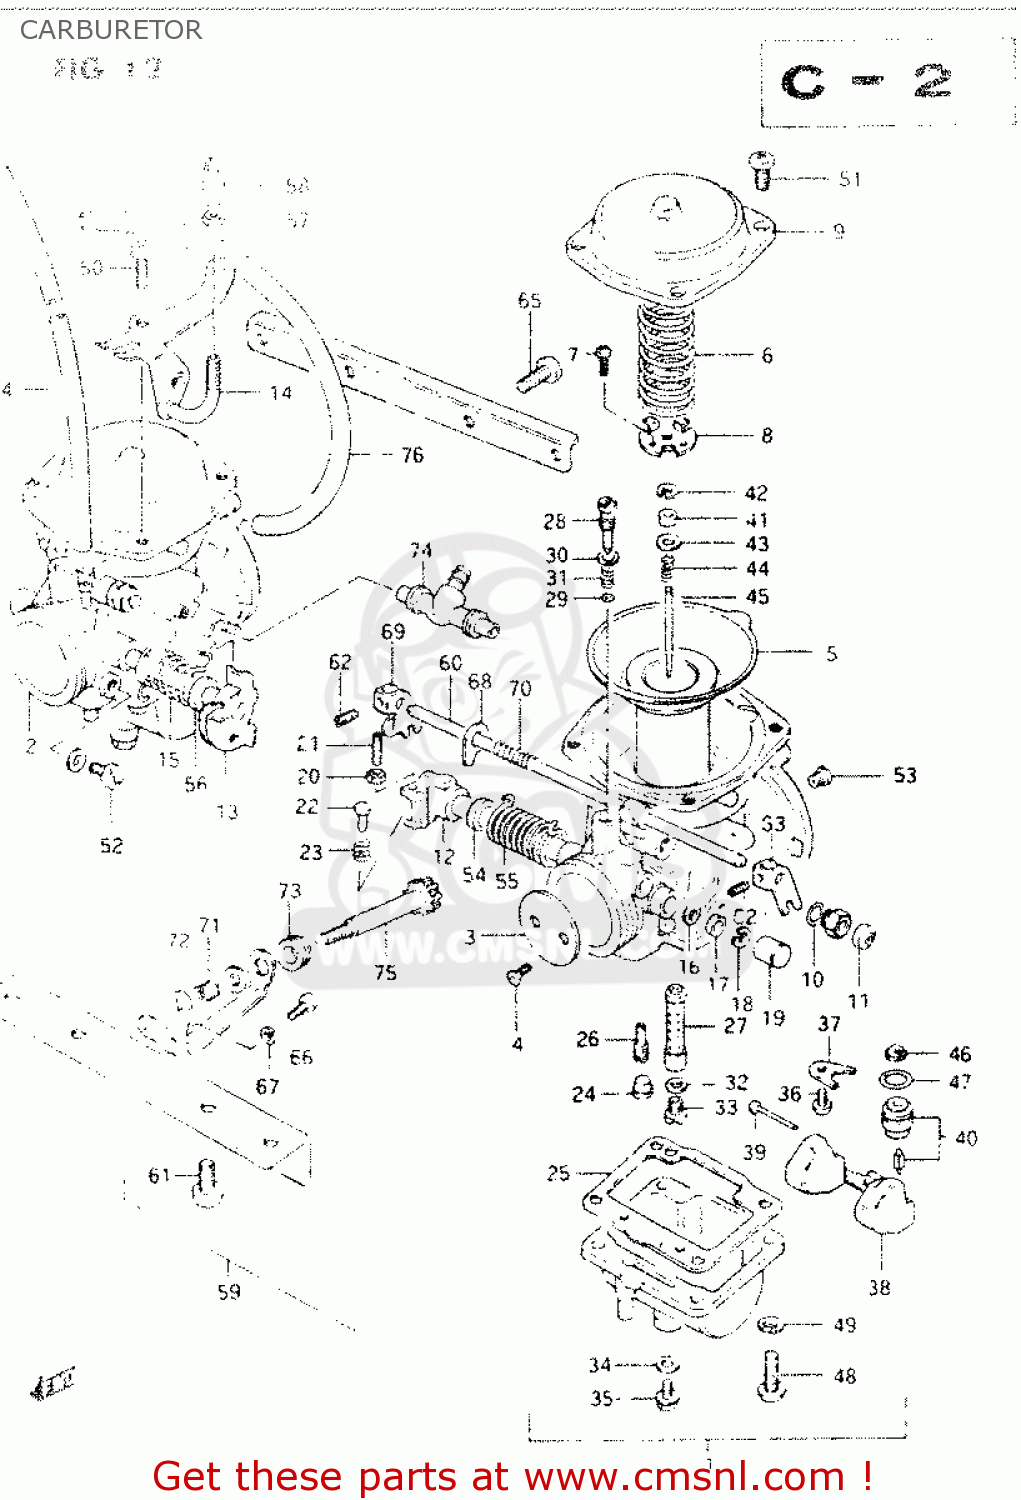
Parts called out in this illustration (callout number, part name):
1	CARBURETOR, LH
2	CARBURETOR, RH
3	VALVE,THROTTLE
4	SCREW
5	DIAPHRAGM,CARBURETOR
6	SPRING
7	SCREW
8	PLATE
9	COVER, DIAPHRAGM
10	O RING
11	CAP,STARTER VALVE
12	SHAFT ASSEMBLY
13	SHAFT,THROTTLE
14	BRACKET
15	SPRING
16	SEAL
17	GASKET,THROTTLE SHAFT (NAS)
18	E RING
19	CAP
20	NUT
21	SCREW
22	PIN,THROTTLE LEVER
23	SPRING,THROTTLE SCREW
24	PLUG,NEEDLE JET
25	GASKET,FLOAT CHAMBER (NAS)
26	JET,PILOT(42.5)
27	JET,NEEDLE(P-1)
28	SCREW,PILOT AIR
29	O-RING
30	GASKET
31	SPRING
32	WASHER,NEEDLE NOZZLE
33	JET,MAIN(120)
34	GASKET (NAS)
35	PLUG,DRAIN
36	SCREW
37	PLATE,NEEDLE VALVE FITING
38	FLOAT
39	PIN,FLOAT
40	VALVE ASSEMBLY,NEEDLE
41	RING
42	CLIP
43	WASHER,JET NEEDLE
44	SPRING
45	NEEDLE,JET
46	FILTER
47	O-RING,NEEDLE VALVE
48	SCREW
49	LOCK WASHER
50	SCREW 5X10
51	SCREW
52	SCREW
53	JET,AIR(125)
54	SPACER,THROTTLE SHAFT
55	SPRING
56	SPACER,THROTTLE SHAFT
57	NUT
58	ADJUSTER
59	FLANCE ASSY
60	SHAFT,STARTER
61	SCREW
62	SCREW
63	LEVER
64	HOSE 4.5X8X390
65	SCREW 5X12
66	SCREW
67	LOCK WASHER
68	PLATE
69	LEVER,STARTER
70	SPRING,STARTER
71	SPRING,THROTTLE ADJUST
72	BRACKET,THROTTLE ADJUST
73	CAP,RUBBER
74	NIPPLE,CARBURETOR
75	SCREW
76	HOSE
